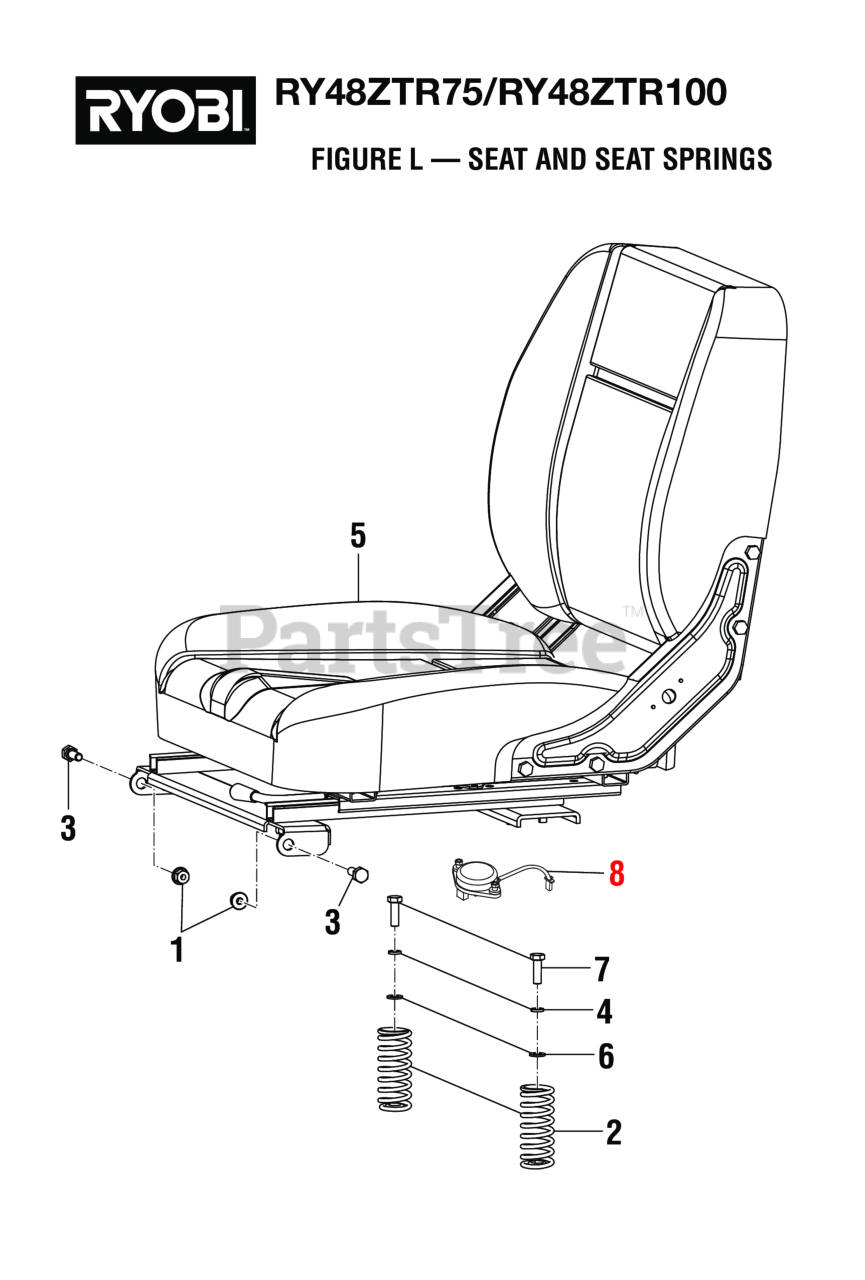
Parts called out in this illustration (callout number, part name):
1	Flange Nut (M8) (For Drive Motor Controller V)
2	Seat Spring, ZTR
3	Shoulder Bolt (M8 x 20 mm)
4	Lock Washer (OD9.8 x ID8.5 x 5t)
5	Seat, ZTR
6	Washer (OD16 x ID8.4 x 1.6t)
7	Bolt (M8 x 25 mm, Hex Hd.)
8	Seat Switch
